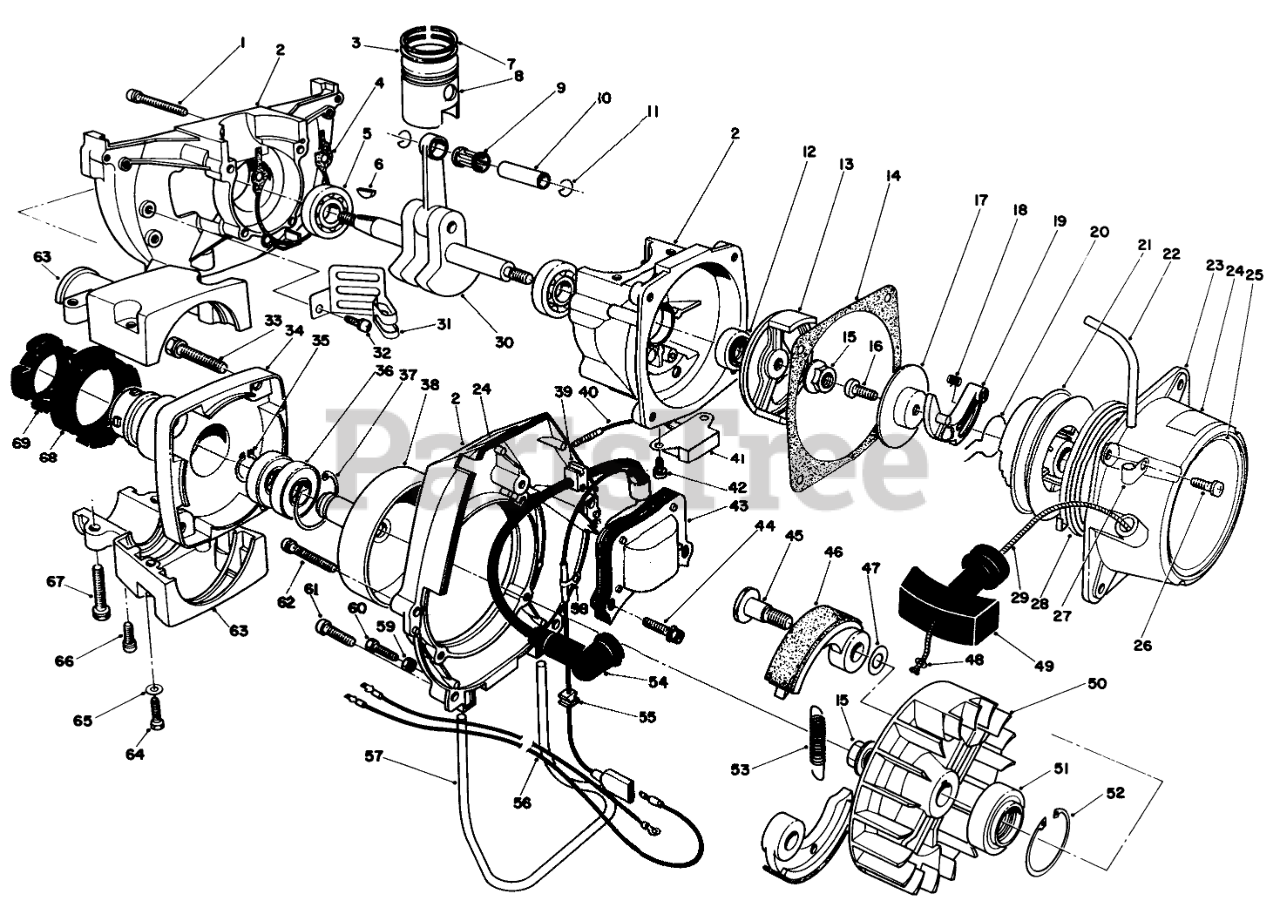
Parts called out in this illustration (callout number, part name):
1	SCREW & WASHER
2	Crankcase (Incl. Ref. #1 & 61)
3	RING,PISTON
4	GASKET,CASE
5	BALL BEARING
7	RING,PISTON
8	Piston Set (Incl. Ref. #10)
9	BEARING, NEEDLE
10	PIN, PISTON
11	CLIP, PISTON PIN
12	OIL SEAL
13	PULLEY, STARTER
14	GASKET, STARTER
16	Screw
17	PLATE, FRICTION
18	SPRING, RETURN
19	RATCHET
20	SPRING, FRICTION
22	Tube-Fuel
23	Recoil-Starter (Incl. Ref. #13, 16-21, 24, 25, 28, 29, &49)
24	DECAL HOT
25	TORO DECAL
26	Screw
27	Clamp
28	SPRING, SPIRAL
29	Rope-Starter
30	Crankshaft (Incl. Ref. #6&9)
31	Clamp
32	Screw & Washer
34	CASE, CLUTCH
35	SNAP RING
36	BALL BEARING
37	SNAP RING
38	DRUM, CLUTCH
39	Grommet
40	WIRE, LEAD
41	Unit-Transistor (Incl. Ref. #40)
42	SCREW & WASHEROR
43	COIL, IGNITION
44	BOLT AND WASHER
45	BOLT,CLUTCH
46	Shoe-Clutch
47	WASHER
48	WASHER
49	Knob-Starter
50	FLYWHEEL
51	OIL SEAL
52	SNAPRING
53	SPRING
54	CAP-PLUG
55	GROMMET
56	WIRE,LEAD
57	TANK GUARD
58	Clamp
61	Screw
62	Screw
63	VV2DER
65	Washer
66	SCREW & WASHER
67	BOLT-WASHER/ENG
68	RUBBER, CUSHION (A)
69	RUBBER, CUSHION (B)
